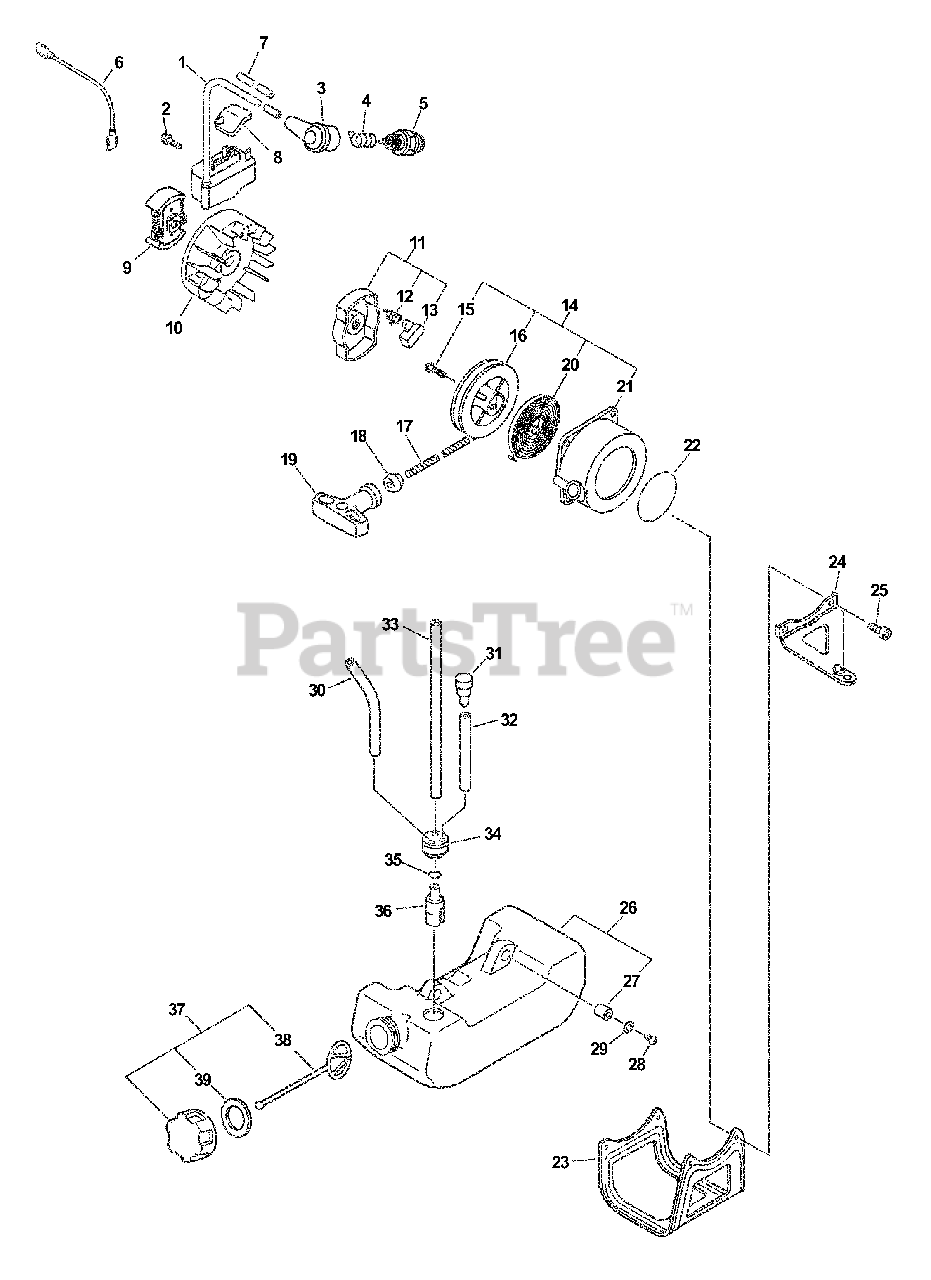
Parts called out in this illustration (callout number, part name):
1	COIL, IGNITION
2	SCREW - 4X20
3	CAP, SPARK PLUG
4	TERMINAL, SPARK PLUG CAP
5	SPARK PLUG -- BPM-8Y
5	SPARK PLUG -- BPMR-8Y
6	LEAD - IGNITION
7	TUBE, INSULATOR
8	COVER, DUST
9	CLUTCH ASSY
10	FLYWHEEL
11	STARTER PAWL ASSY
12	SPRING, RETURN
13	PAWL, STARTER
14	STARTER ASSY
16	REEL, ROPE
17	ROPE, STARTER - 3X1000
18	GUIDE, ROPE
19	GRIP, STARTER
20	SPRING, REWIND
21	CASE, STARTER
22	LABEL - ECHO
23	GUARD, FUEL TANK
24	SUPPORT, REAR HANDLE
25	SCREW - 4X16
26	TANK, FUEL
28	SCREW - 5X16
29	WASHER - 5
30	PIPE - 3X6X80 -- CLEAR
31	VENT, FUEL TANK
32	PIPE - 3X5X30 -- BLACK
33	PIPE - 3X5X160 -- BLACK
34	GROMMET
35	CLIP - 6
36	FILTER, FUEL
37	CAP ASSY - ORANGE
38	CONNECTOR, CAP
39	GASKET, CAP
